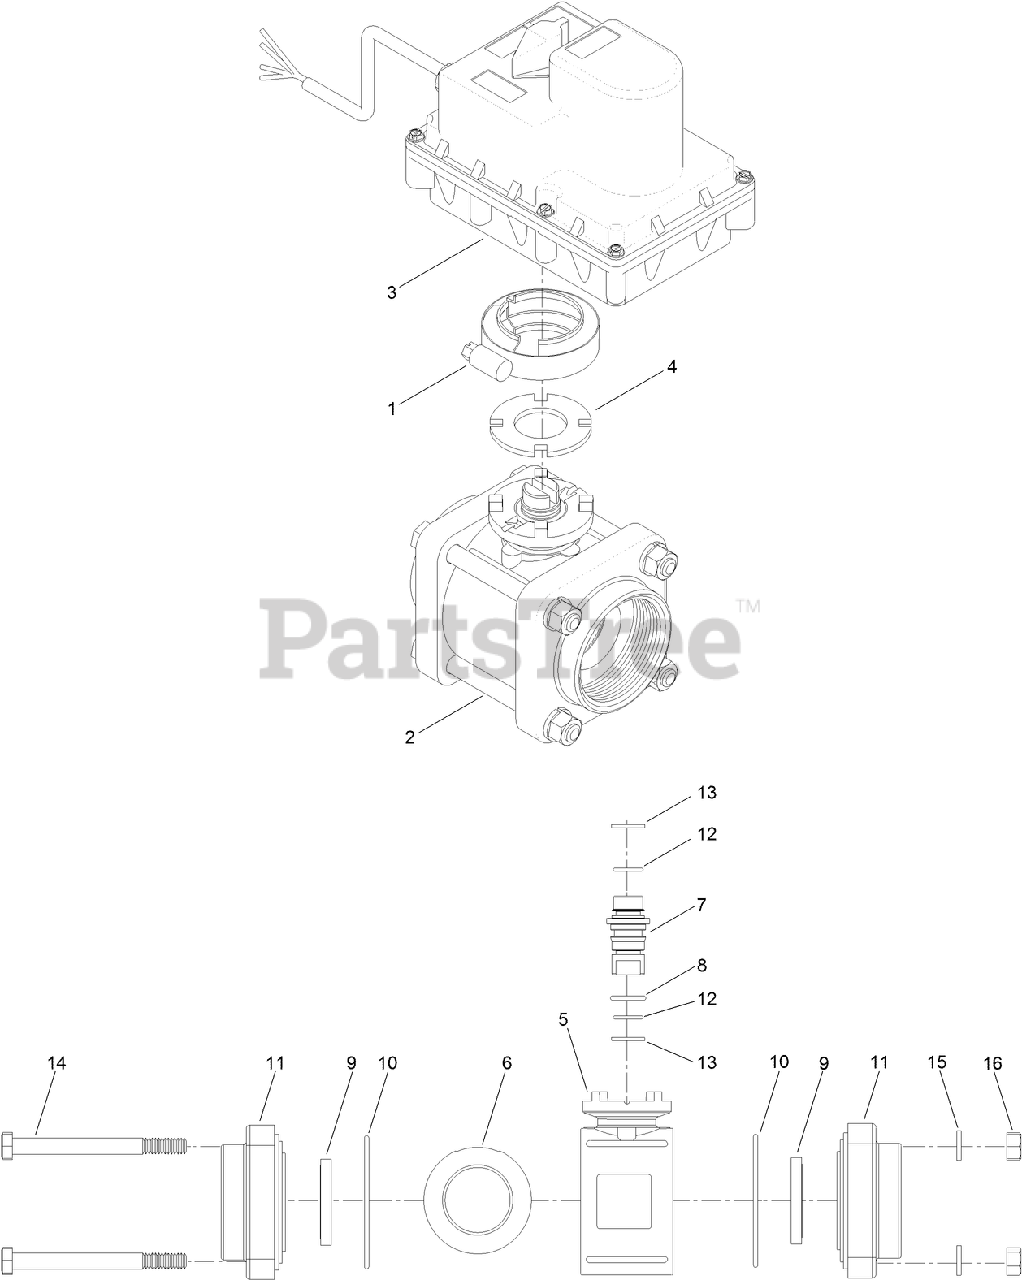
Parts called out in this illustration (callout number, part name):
1	CLAMP-FLANGE
4	FILTER
5	BODY-VALVE
6	BALL-HOLLOW
7	STEM-VALVE
8	O-RING
9	SEAT-VALVE
10	O-RING
11	PLATE-END
12	O-RING
13	SEAL-VALVE
14	SCREW-HH
15	WASHER-LOCK
